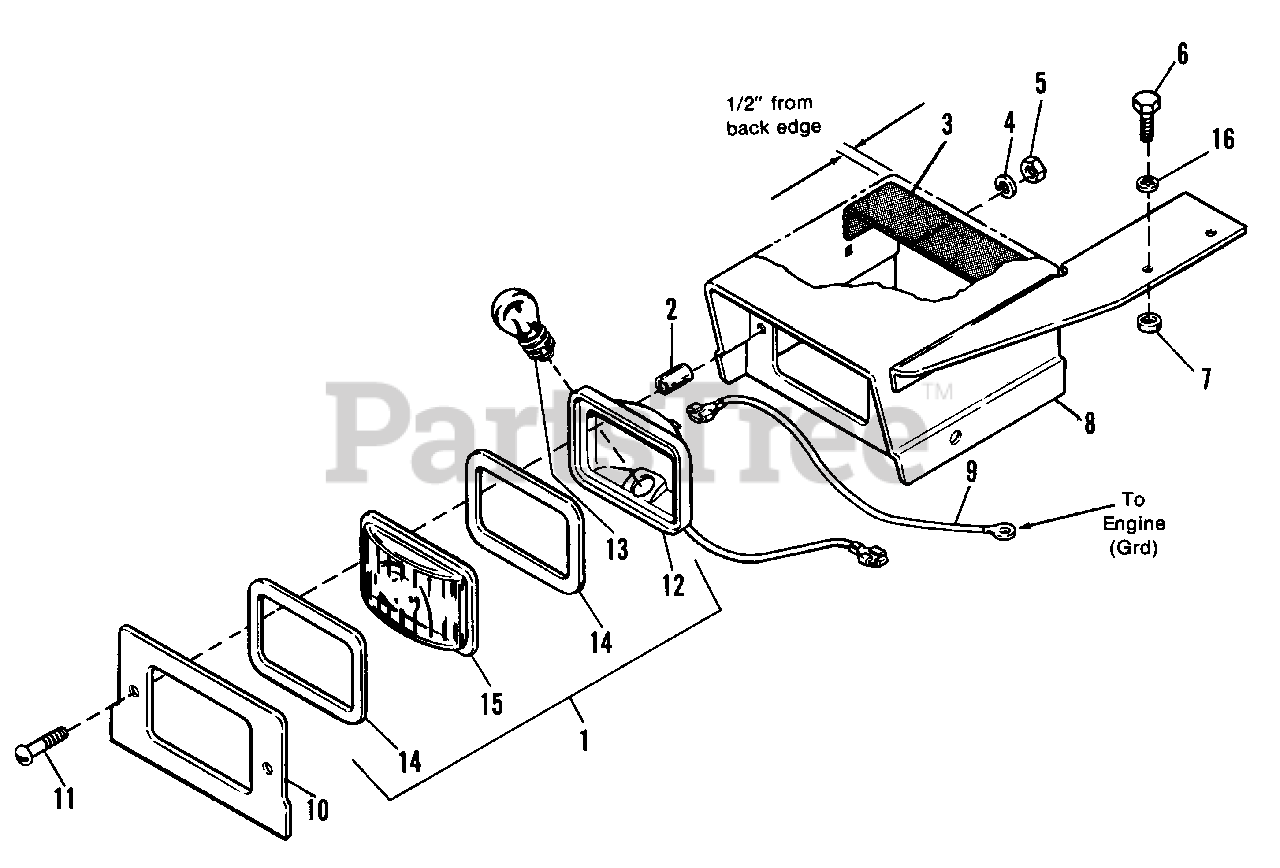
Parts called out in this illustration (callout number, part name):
1	LIGHT ASSY. (Incl. Ref. Nos. 12 thru 15)(1691775, 1691776, 1691779)
1	LIGHT ASSY. (Incl. Ref. Nos. 12 thru 15)(1691898, 1691899, 1691947, 1691948)
3	PAD, Rubber
4	LOCKWASHER, 1/4
5	NUT, Hex, 1/4-20
6	CAPSCREW, Hex Hd., 5/16-18 x 1
7	WASHER, Plain, 5/16 x 1 O.D.
8	COVER ASSY., Headlight
9	WIRE, Light to Ground
10	SUPPORT, Light
11	SCREW, Rd. Hd., 1/4-20 x 1
12	SOCKET, Reflector (1691775, 1691776, 1691779)
12	SOCKET, Reflector (1691898, 1691899, 1691947, 1691948)
15	LENS, Amber
16	LOCKWASHER, Internal Tooth, 5/16
